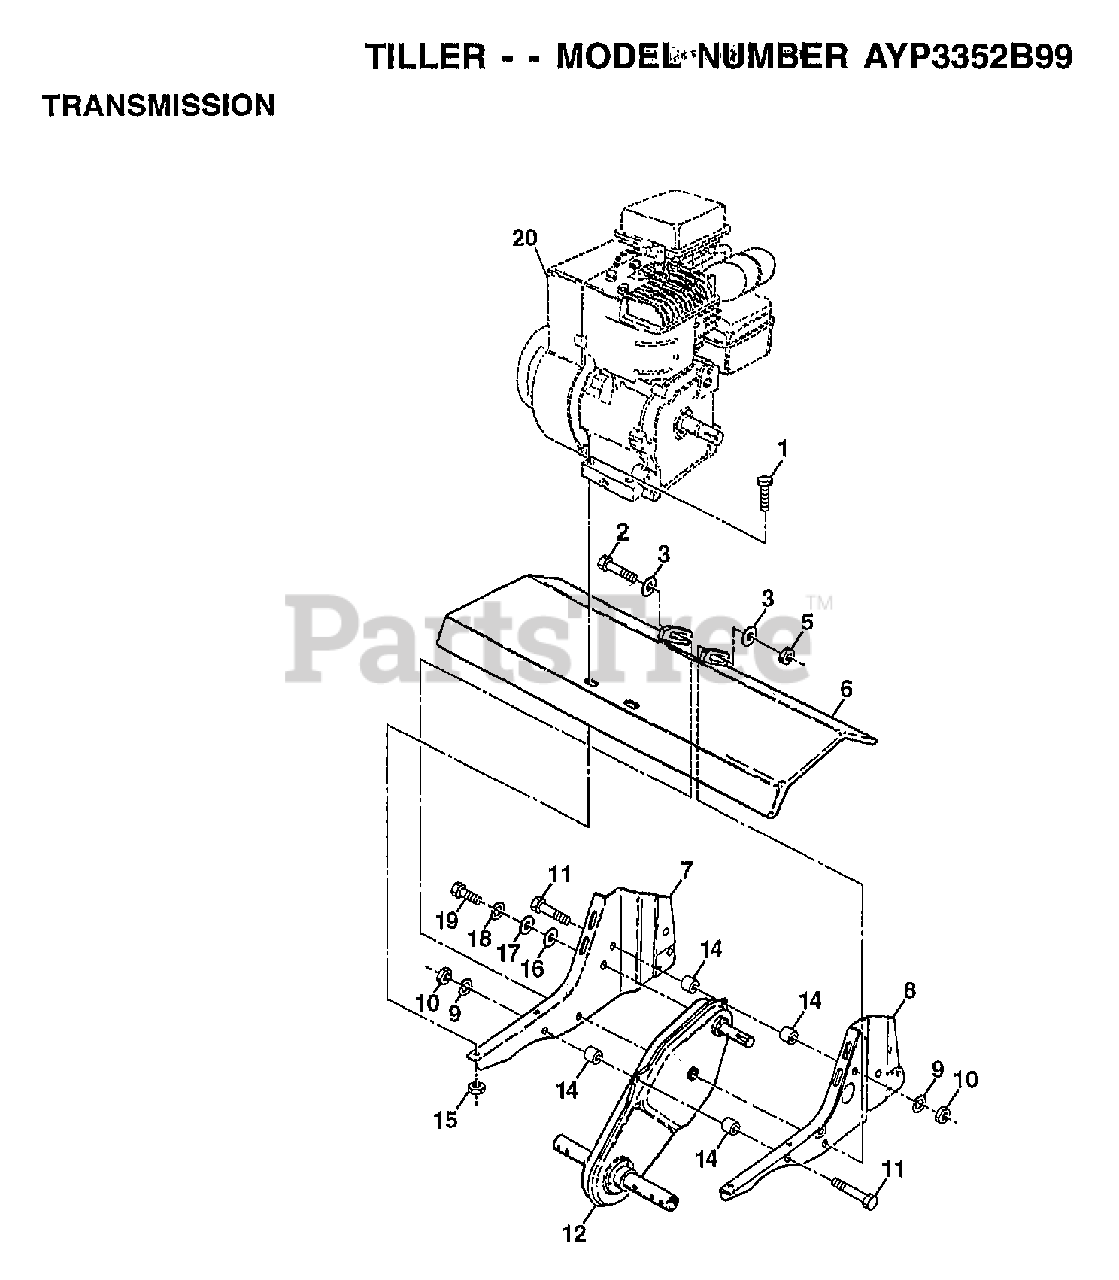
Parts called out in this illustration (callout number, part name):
1	BOLT.HEX.5/16-1.5
2	BOLT HEX 3/8-16
3	WASHER
5	NUT
6	"SHIELD, TINE"
7	BRACKET.ENGINE.RH
8	BRKT.ENGINE.LH
9	LOCKWASHER
10	NUT.HEX.5/16-18
14	SPLIT SPACER RT
16	WASHER
17	WASHER
18	LOCKWASHER
19	BOLT
